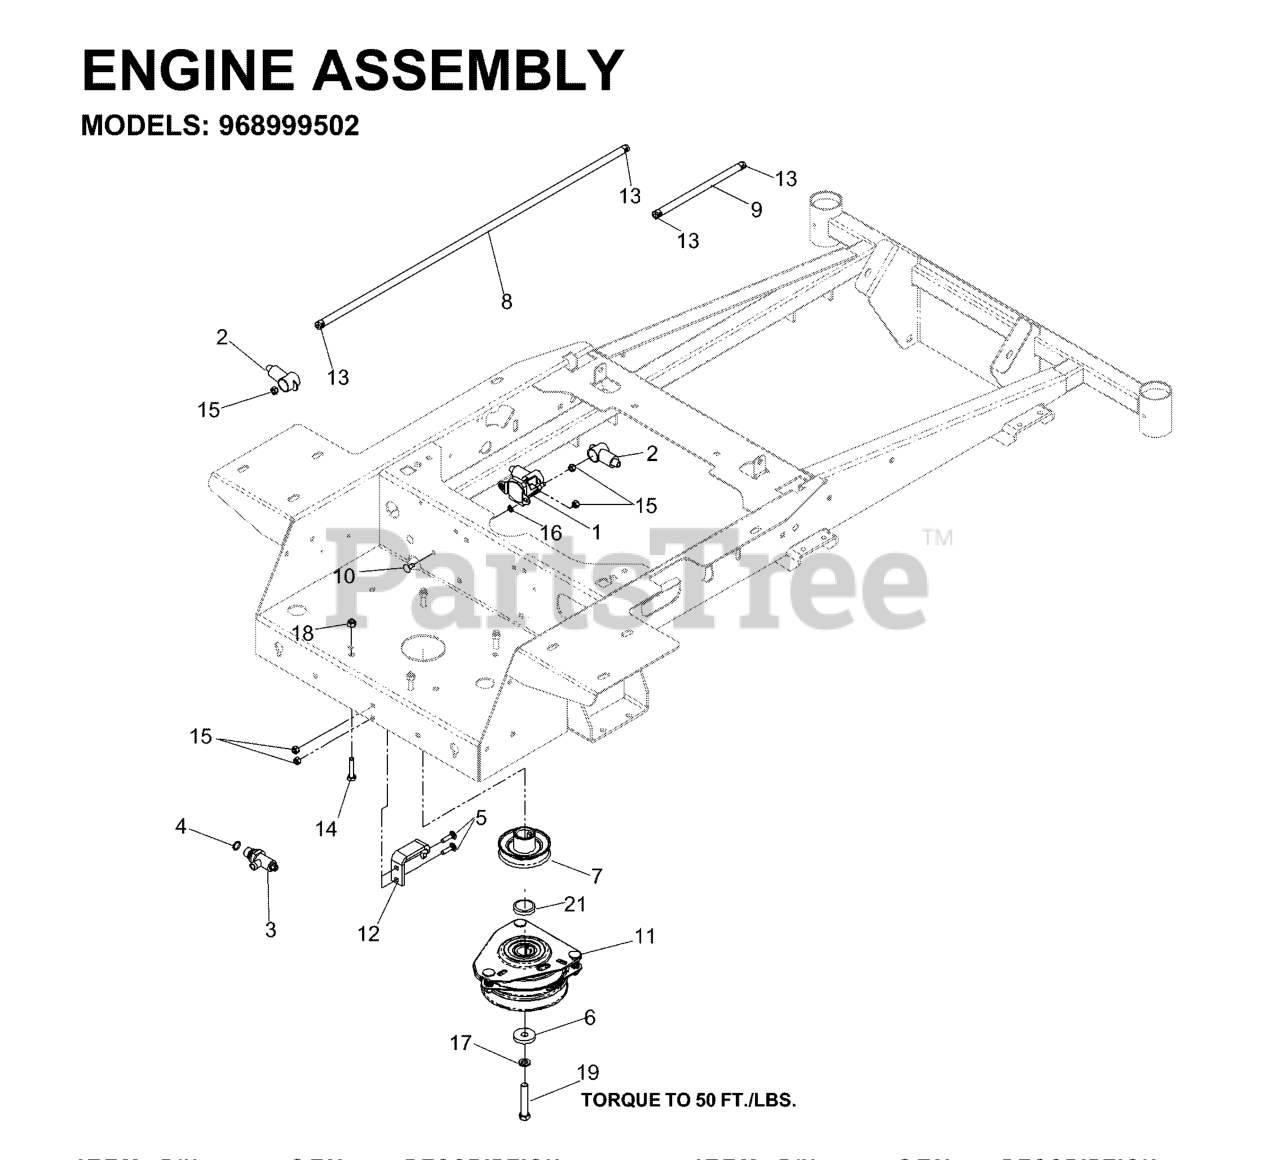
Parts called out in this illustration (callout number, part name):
3	VALVE ASSEMBLY
5	RHSNB, 1/4-20 X 1, GR5
6	CLUTCH, WASHER
8	FUEL LINE 24"
9	FUEL LINE 5"
10	RHSSNB, 1/4-20X5/8
11	CLUTCH, 90 FT/LBS
12	CLUTCH TIE DOWN
13	HOSE CLAMP
14	CAPSCREW 5/16 X 1/1/2 HEX HEAD
15	NUT.1/4-20.HEX.NYLOC.ZD
16	WASHER 1/4 INT TOOTH
17	WASHER 7/16 LOCK
18	NUT 5/16 NYLOC
19	HCS 7/16-20X3-1/2 GR 5 ZN
20	HCS 5/16C X 3/4
21	SPACER, ENGINE, PULLEY
